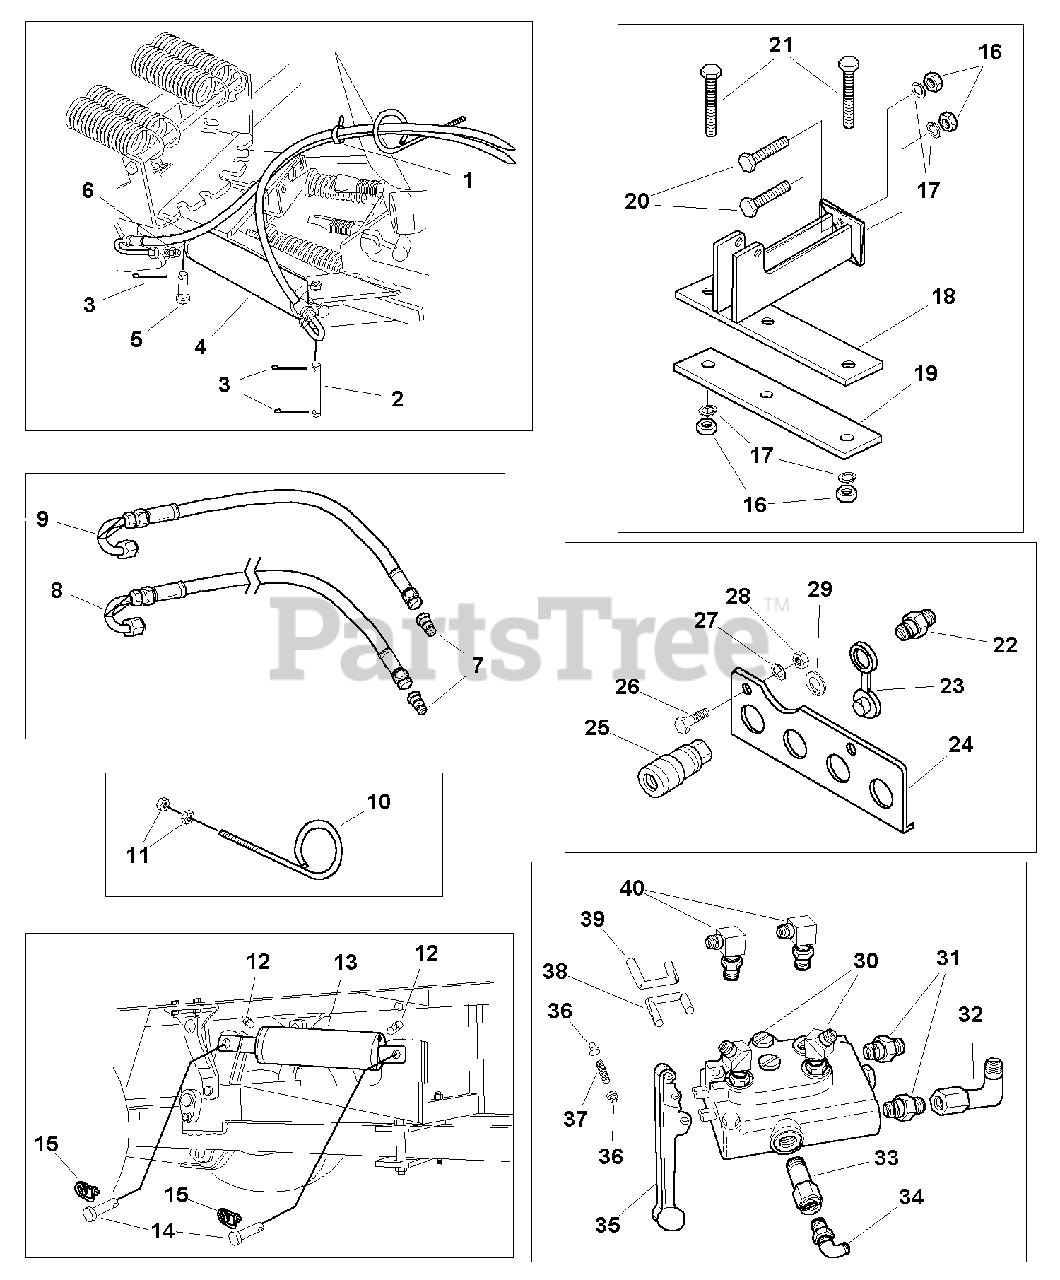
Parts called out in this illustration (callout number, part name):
1	TIE, Self Locking
3	PIN, Cotter
4	ANGLING CYLINDER ASSEMBLY
5	PIN, Flat Head, 5/8 x 1-5/8
6	TUBE FITTING, Male
7	NOSE PIECE ASSEMBLY
8	HOSE ASSEMBLY, 17" Long
9	HOSE ASSEMBLY, 50" Long
10	HOSE SUPPORT
11	NUT, Hex, 5/16-18
12	TUBE FITTING, Male
13	LIFT CYLINDER ASSEMBLY
14	PIN, Clevis
15	PIN, Saftey
16	NUT, Hex, 1/2-13
17	LOCKWASHER, 1/2
18	SUPPORT ASSEMBLY, Cylinder
19	CLAMP, Plate
20	CAPSCREW, Hex Head,1/2-13 x 1-1/2
21	CAPSCREW, Hex Head,1/2-13 x 3-1/2
22	FITTING, Tube Male
23	PLUG, Plastic
25	COUPLER ASSEMBLY
26	CAPSCREW, Hex Head, 1/4-20 x 3/4
27	LOCKWASHER, 1/4
28	NUT, Hex 1/4-20
29	RETAINING RING
30	FITTING, Hose, 45 Degree
31	FITTING, Tube Male
32	FITTING, Elbow, 90 Degree
33	PLUG, Pressure
34	FITTING, Elbow, 90 Degree
35	LEVER ASSEMBLY
40	FITTING, Elbow
